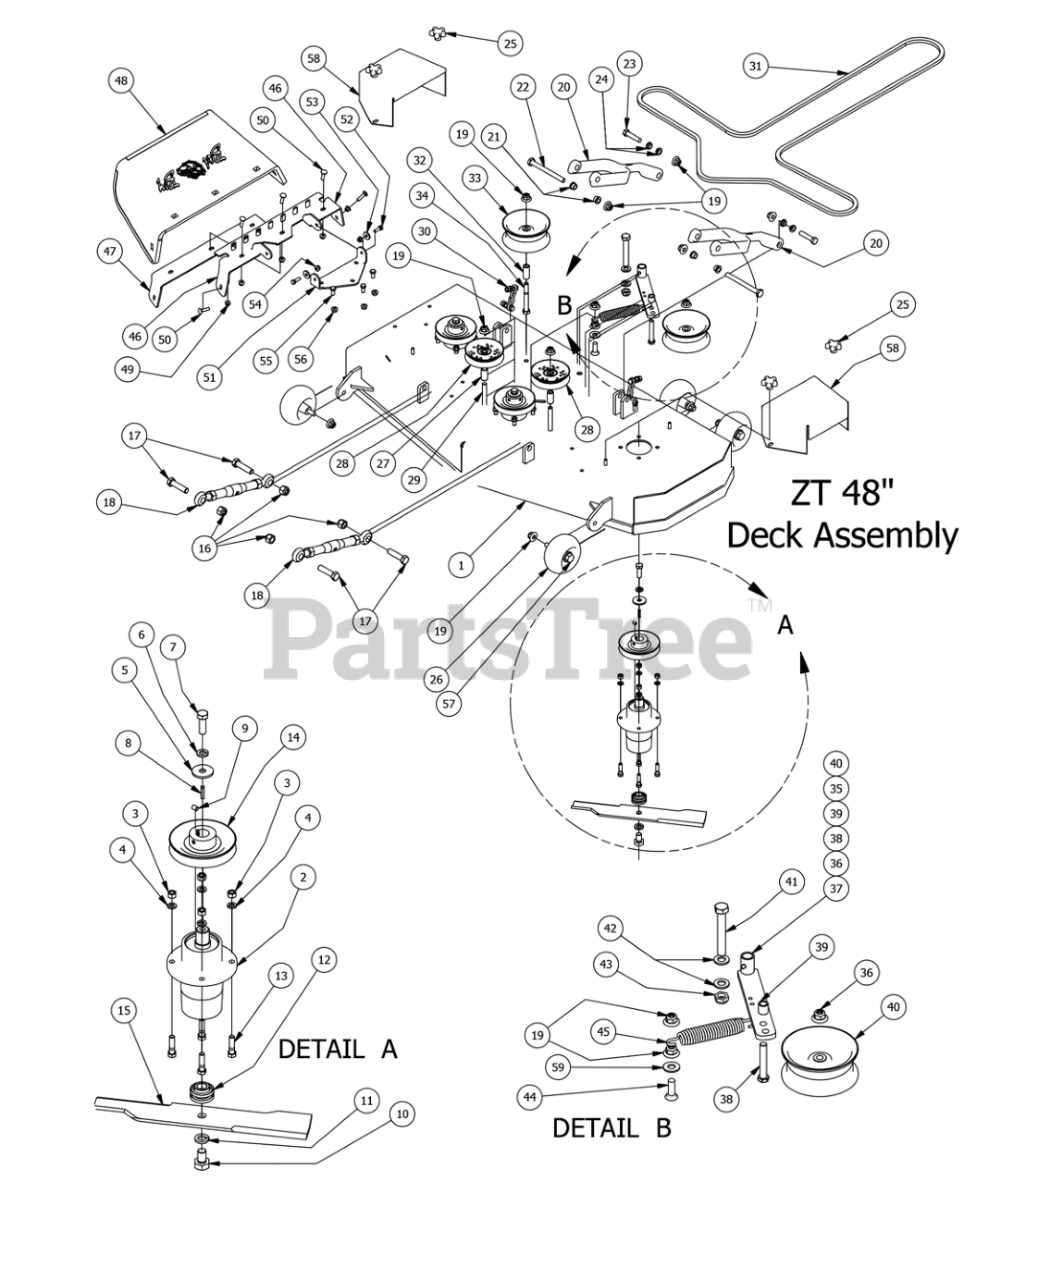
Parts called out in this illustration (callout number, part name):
1	2014 ZT/CZT 48" Deck
2	Spindle - Aluminum
3	3/8" Hex Nut
4	3/8" Lock Washer
5	1/2 Belleville Washer
6	1/2" Lock Washer
7	1/2"-20 x 1 1/2 - Grade 5 Fine Thread Bolt
8	1/4" x 1" Key
9	5/16 Set Screw
10	5/8" x 1 1/2" Grade 8 Bolt
11	5/8" Lock Washer
12	Spindle Bearing
13	3/8-16 X 1-1/4 GR 5 Hex Bolt
14	5" Deck Pulley
15	48" ZT Blade With Fusion
16	5/8 Std NC Nylock Nut
17	5/8" x 2 1/2" Hex Bolt
18	Turnbuckle (Top Link)
19	1/2-13 Nylon Flange Nut-Orange
20	Deck Arm Assembly
21	Flange Bushing For Deck Arm upper
22	1/2" x 5 1/2" Bolt
23	1/2-13X 2-1/4 GR Hex Bolts
24	Flange for Lower Deck Arm
25	5/16" Knob
26	Deck Wheel
27	.502 ID X.75 OD X 1.500 Leng
28	4-3/4 Idler Pulley
29	1/2 x 3 1/2 Flange Bolt Grade 8
30	Chain assembly
31	50" Deck Belt
32	1 3/4" Pulley Spacer
33	5 3/4" Deck Idler Pulley
34	1/2" x 4" Bolt (Grade 8)
35	Deck Idler Assy Components (36,37,38,39,40)
36	1/2-13 Nylon Flange Nut-Orange
37	Deck Idler
38	1/2-13 x GR 5 Hex Bolt Zinc
39	3/4 OD x 1/2 ID x 3\4 Length
40	5 3/4" Deck Idler Pulley
41	5/8" x 4" Hex Bolt
42	.635 ID Plastic Washer
43	5/8-11 Nylon Insert Jam Half Nut
44	1/2 x 1-1/2 Carriage Bolt
45	2009 Deck/Pump Idler Spring
46	Upper Hanger
47	Discharge Lower Chute Bracket
48	Rubber Discharge Chute
49	5/16" Nylon Flange Nut
50	5/16" x 1 1/4" Carriage Bolt
51	Discharge Chute Hanger (deck mounted)
52	5/16" x 1" Bolt
53	.360 ID Plastic Washer
54	5/16" Nylon Flange Nut
55	3/8" x 3/4" Hex Bolt
56	3/8" Flange Nut
57	Deck Wheel Bolt
58	Pulley Cover
59	1/2" Washer (Grade 8)
